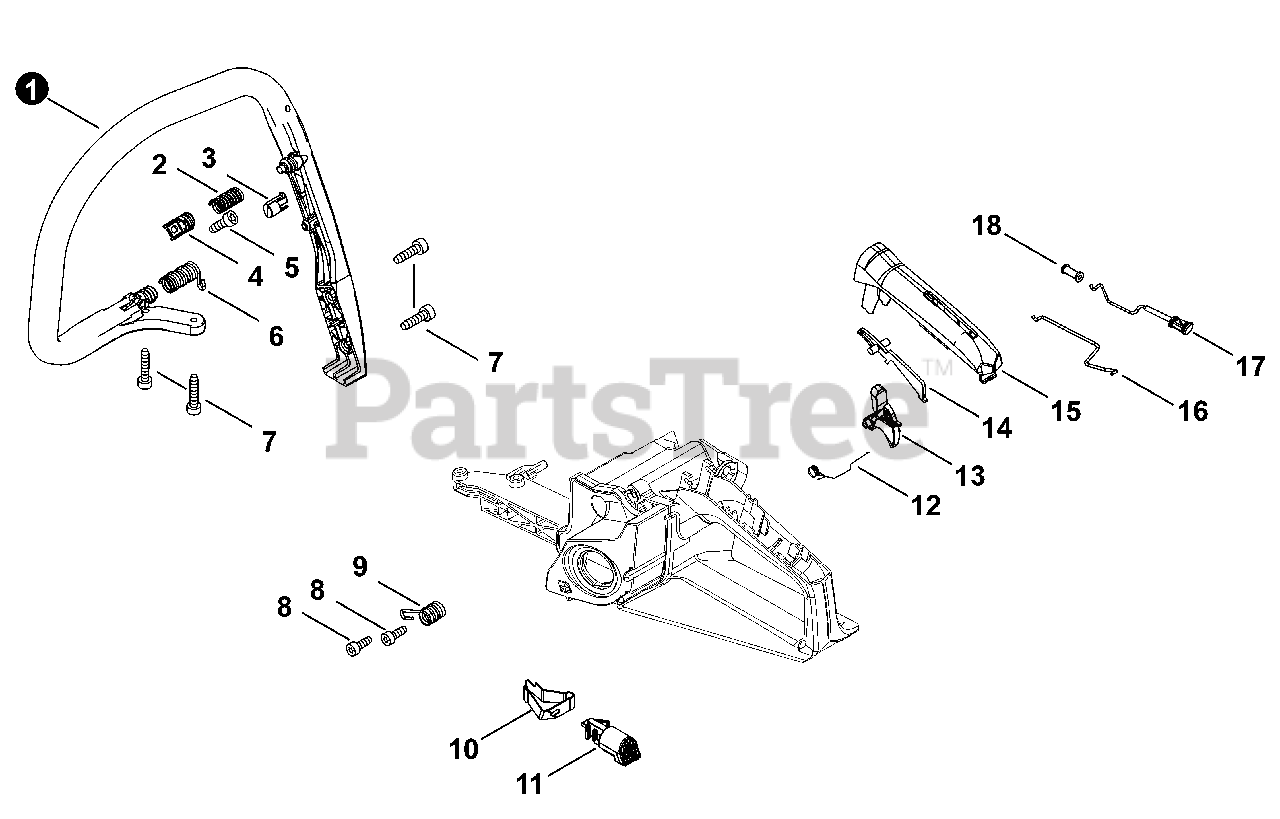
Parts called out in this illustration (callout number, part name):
1	HANDLE, FRONT
2	SPRING, COMPRESSION
3	CUSHION
4	HOLDER, SPRING
5	BOLT, TORX 5×12
6	SPRING, COMPRESSION
7	BOLT, TORX 5×20
8	BOLT, TORX 5×12
9	SPRING, COMPRESSION
10	TERMINAL, LEAD
11	SWITCH, MOMENTARY STOP
12	SPRING, TORSION
13	TRIGGER, THROTTLE
14	LEVER, THROTTLE LOCKOUT
15	COVER, HANDLE
16	ROD, THROTTLE
17	KNOB, CHOKE
18	GROMMET, CHOKE
